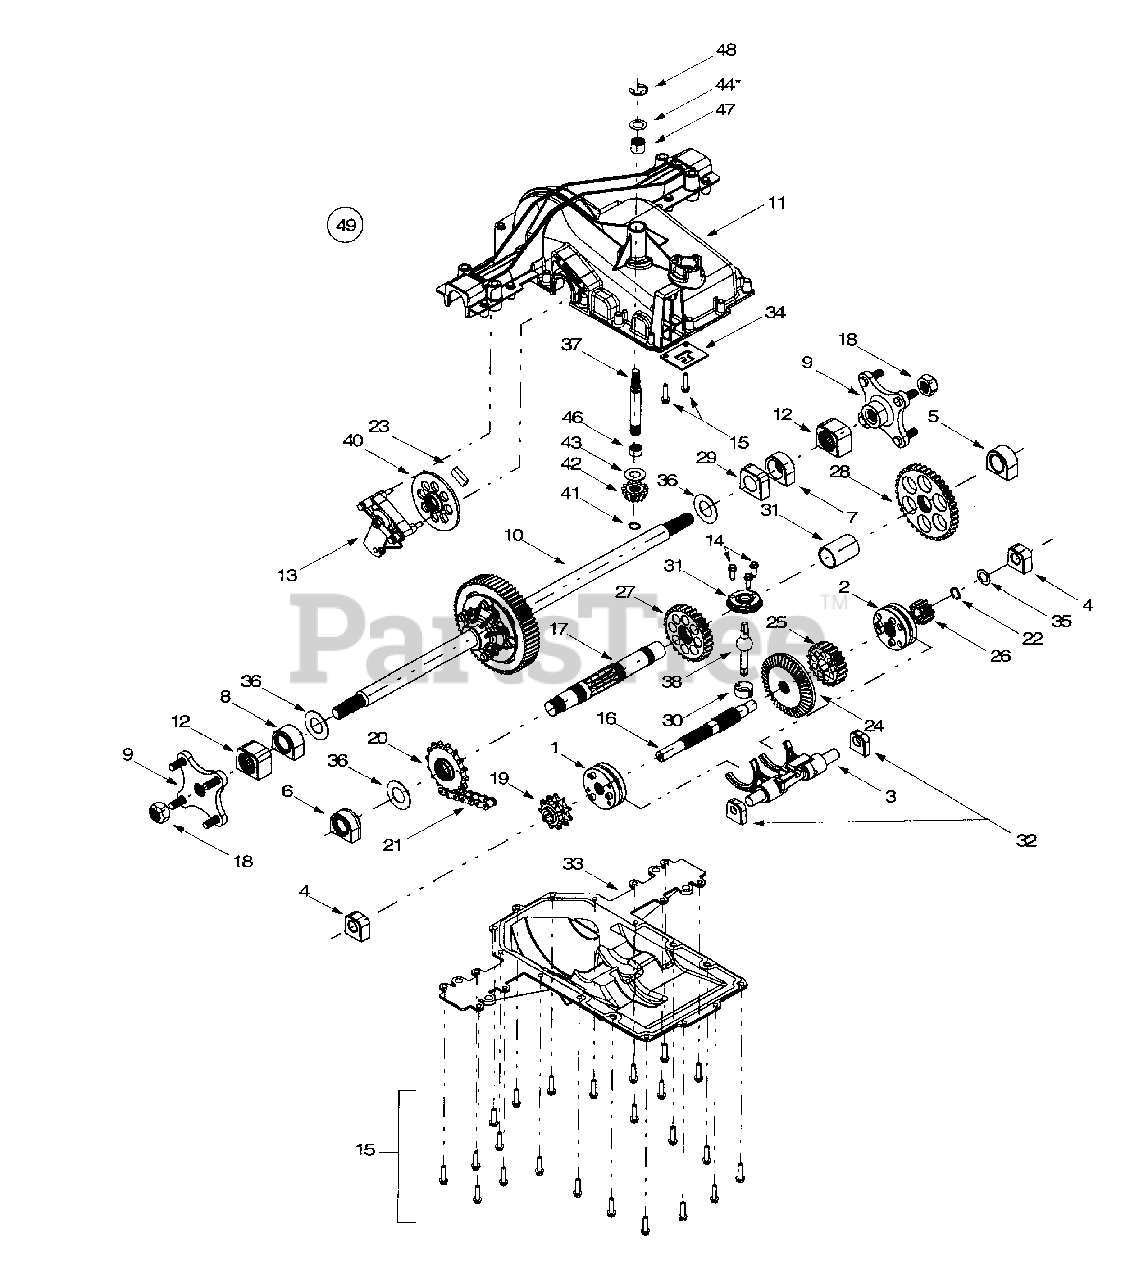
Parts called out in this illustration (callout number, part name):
1	Reverse Collar Assembly
2	Hi-Lo Collar Assembly
3	Shift Fork Assembly
4	Detent Block Assembly
5	Output Bearing Block Assembly
6	Output Seal Bearing Block Assembly
7	Inboard Sealed Axle Block Assembly
8	Inboard Sealed Axle Block Assembly
9	Wheel Hub Assembly
10	Differential Axle Assembly
11	Upper Housing
12	Axle Bearing Block Assembly
13	Brake Assembly
14	Self-tapping Screw, 1/4-20 x .75
15	Self-tapping Screw, 1/4-20 x 1.0
16	Drive Shaft
17	Output Shaft
18	Nut, 3/4-16
19	9-tooth Sprocket
20	16-tooth Sprocket
21	22-link Chain, .625
22	External Snap Ring
23	Brake Pad
24	41-tooth Bevel Gear
25	20-tooth Spur Gear
26	10-tooth Spur Gear
27	27-tooth Spur Gear
28	37-tooth Spur Gear
29	Inner Axle Bearing Block
30	Shifter Insert
31	Shifter Cover
32	Shifter Bearing Block
33	Lower Housing
34	Lockout Plate
35	Flat Washer, 5/8 x 1.0
36	Flat Washer, 1.01 x 1.86 x .060
37	Input Shaft
38	Shift Lever
40	Disc Brake
41	Retaining Ring, .56
42	13-tooth Bevel Gear
43	Flat Washer
44	Flat Washer, 5/8 x 1.0 x .030
46	Needle Bearing
47	Needle Bearing
48	E-ring, .75
49	Transmission Assembly
